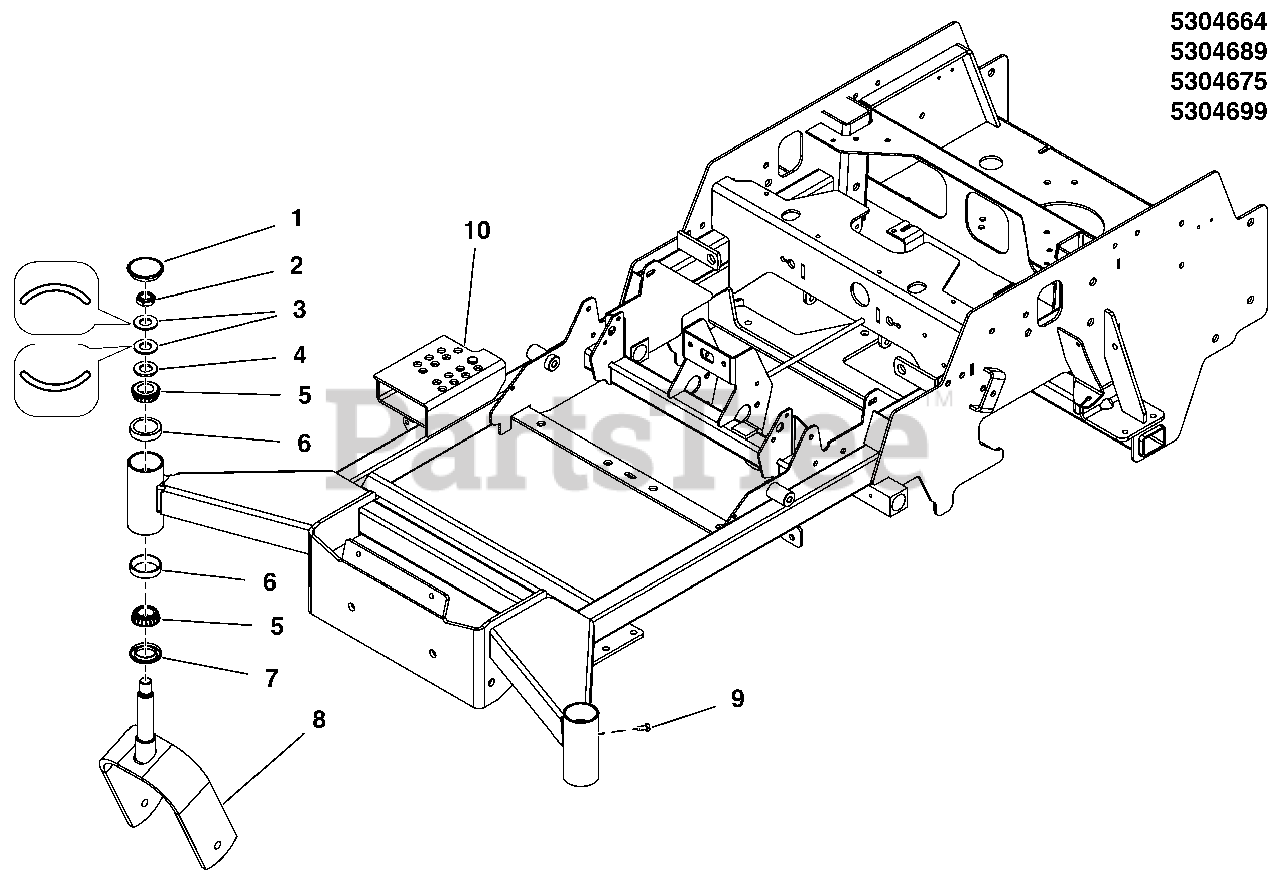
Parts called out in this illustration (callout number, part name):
1	CAP, LOW PROFILE, STEEL
2	NUT, 3/4-16, HEX JAM NYLON LOCK
3	WASHER, BELLEVILLE - 1.500 X .755
4	WASHER, 3/4 SAE
5	BEARING, TAPERED ROLLER, 1
6	BEARING CUP
7	SEAL, GREASE
8	WELD, CASTER YOKE - ORG
9	BOLT, 1/4-28 X 1/2, GD5 CZ
10	* WELD, MAIN FRAME, 560Z - RED
